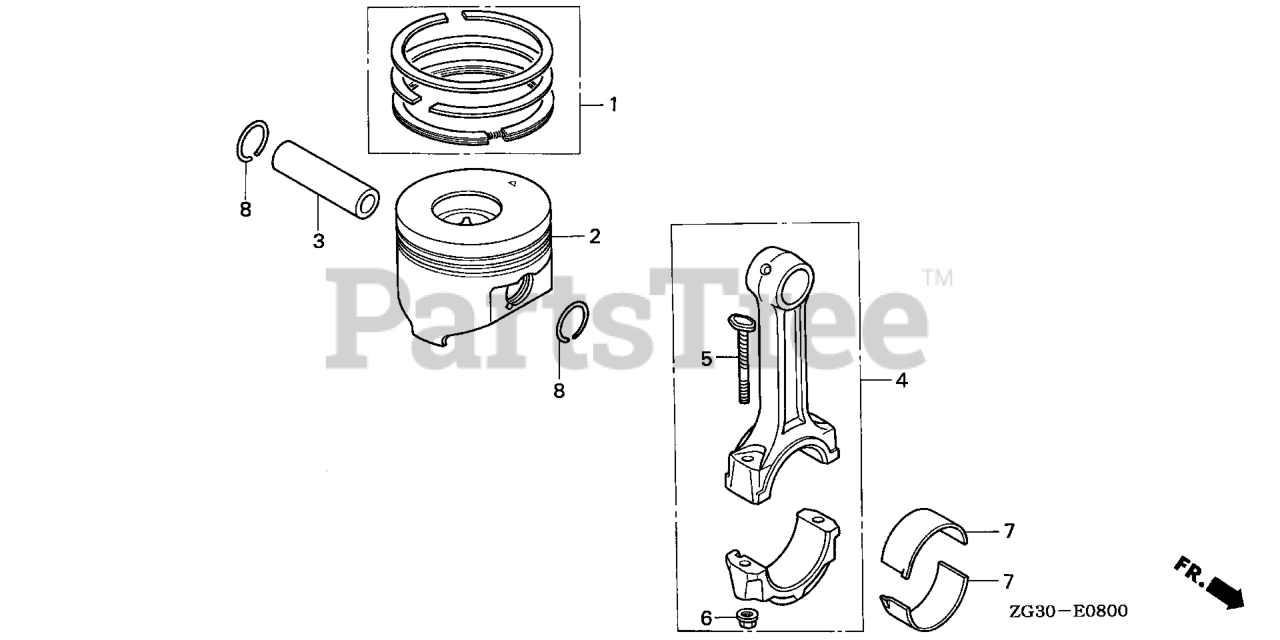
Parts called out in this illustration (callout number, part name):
1	RING SET, PISTON (STD)
1	RING SET, PISTON (OS 0.25)
1	RING SET, PISTON (OS 0.50)
1	RING SET, PISTON (0.75)
2	PISTON (STD)
2	PISTON (OS 0.25)
2	PISTON (OS 0.50)
2	PISTON (0.75)
3	PIN, PISTON
4	ROD ASSY., CONNECTING
5	BOLT, CONNECTING ROD (8X51)
6	NUT, CONNECTING ROD
7	BEARING A, CONNECTING ROD (BLUE)
7	BEARING B, CONNECTING ROD (BLACK)
7	BEARING C, CONNECTING ROD (BROWN)
7	BEARING D, CONNECTING ROD (GREEN)
7	BEARING E, CONNECTING ROD (YELLOW)
7	BEARING, CONNECTING ROD (F)(PINK)
7	BEARING G, CONNECTING ROD (RED)
7	BEARING A, CONNECTING ROD (US 0.25) (BLACK)
7	BEARING B, CONNECTING ROD (US 0.25) (BROWN)
7	BEARING C, CONNECTING ROD (US 0.25) (GREEN)
7	BEARING A, CONNECTING ROD (US 0.75) (BLACK)
7	BEARING B, CONNECTING ROD (US 0.75) (BROWN)
7	BEARING C, CONNECTING ROD (US 0.75) (GREEN)
8	CLIP, PISTON PIN
